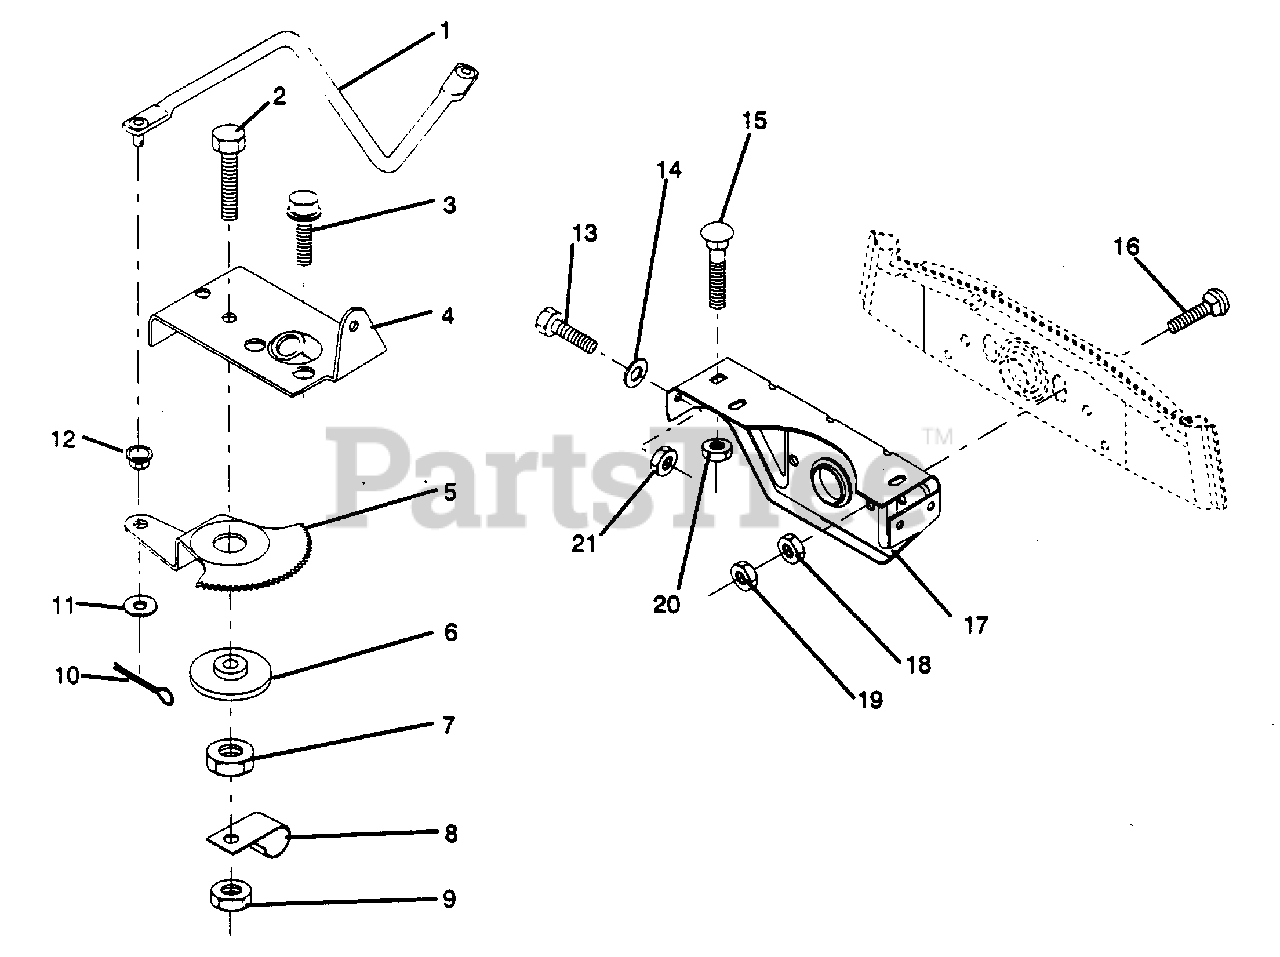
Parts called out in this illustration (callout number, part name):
1	Link, Drag
2	Bolt, Fin. Hex 1/2-13 x 1 3/4
3	Screw Hex Washer Hd. Thrdrol 5/16-18 x 1/2
4	Plate, Steering Support
7	Nut, Heavy Hex Top Lock 1/2-13 UNC
8	Clip, Insulated
9	Nut, Crownlock 1/2 x 13 UNC
10	Pin, Cotter 1/8 x 3/4
11	Washer, 13/32 x 13/16 x 16 Ga.
13	Bolt, Hex Hd. 5/16-18 UNC x 3/4
14	Washer 11/32 x 7/8 x 16 Ga.
15	Bolt, Carriage 3/8-16 UNC x 3/4
16	Bolt, Carriage
17	Support, Front Axle
18	Nut, Fin. Hex 3/8-16 UNC
19	Nut, Centerlock 3/8-16 UNC
20	Nut, Crownlock 3/8-16 UNC
21	Nut, Crownlock 5/16-18
